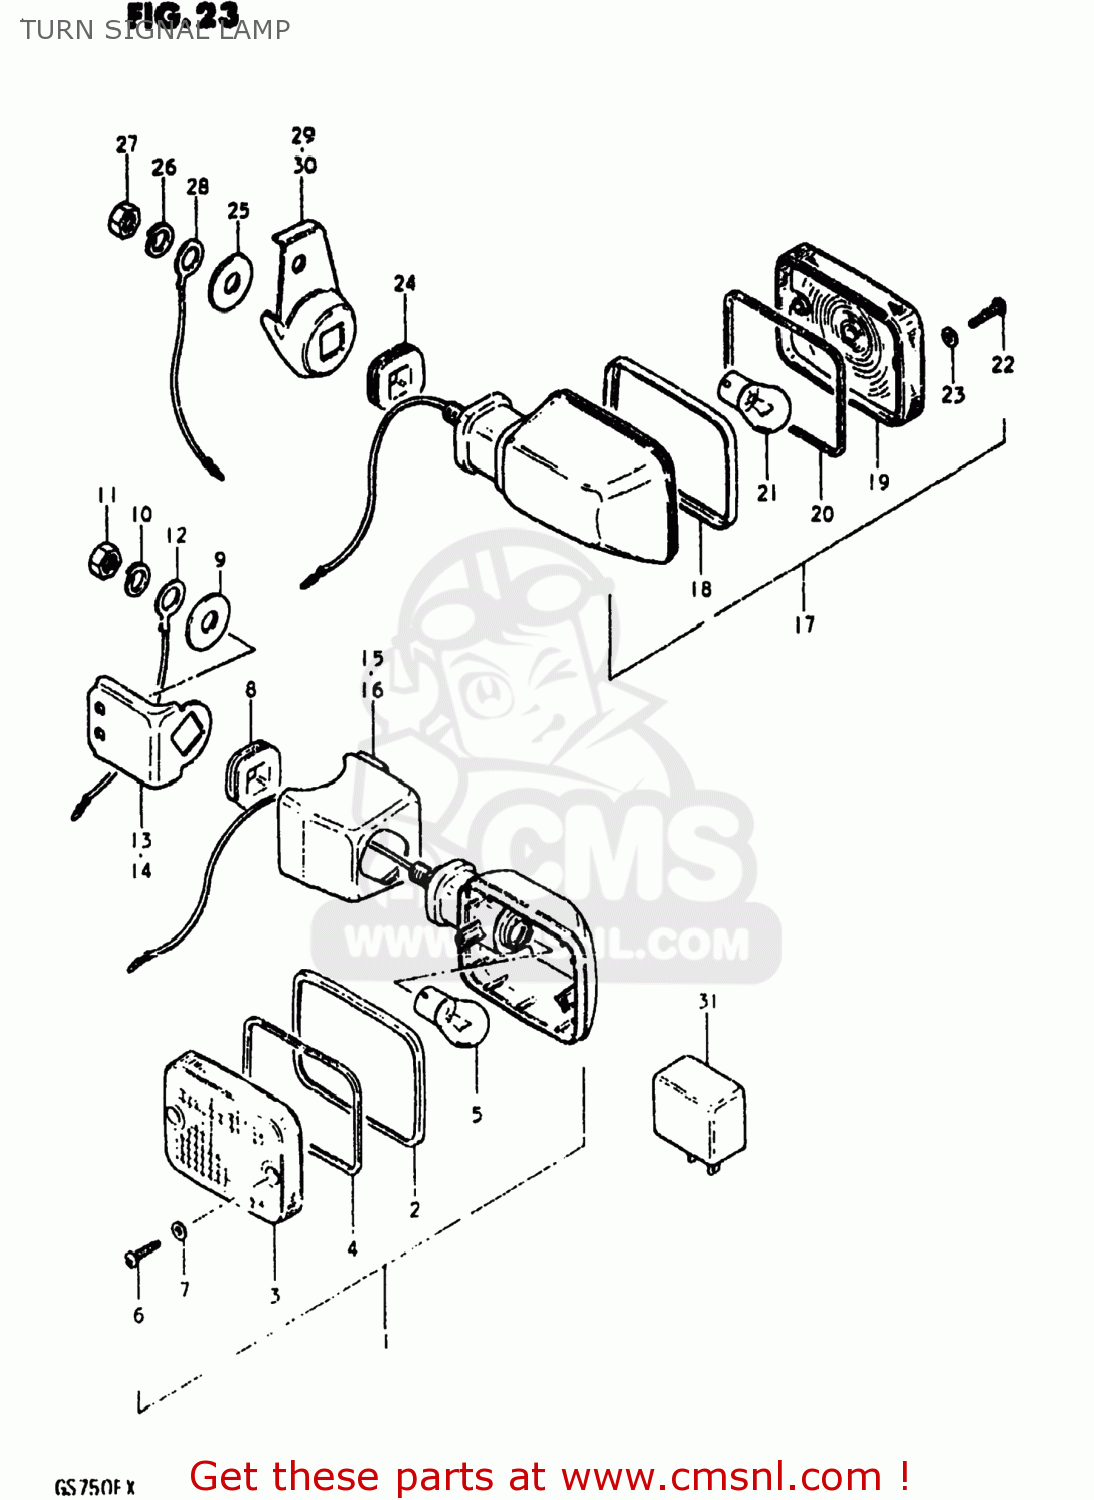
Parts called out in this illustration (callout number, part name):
1	LAMP ASSEMBLY,FRONT TURN SIGNAL
2	RIM
3	LENS
4	GASKET (NAS)
5	BULB(12V23W,STANLEY,A4577A)
6	SCREW
7	GASKET (NAS)
8	CUSHION
9	WASHER (10.5X30X2.3)
10	LOCK WASHER
11	NUT
12	WIRE,TURN SIGNAL LEAD
13	BRACKET,FRONT TURN SIGNAL
14	BRACKET,FRONT TURN SIGNAL
15	COVER,TURN SIGNAL BRACKET
16	COVER,TURN SIGNAL BRACKET
17	LAMP ASSEMBLY,FRONT TURN SIGNAL
18	RIM
19	LENS
20	GASKET (NAS)
21	BULB(12V23W,STANLEY,A4577A)
22	SCREW
23	GASKET (NAS)
24	CUSHION
25	WASHER (10.5X30X2.3)
26	LOCK WASHER
27	NUT
28	LEAD WIRE,EARTH
29	BRACKET,REAR TURN SIGNAL
30	BRACKET,REAR TURN SIGNAL
31	RELAY,TURN SIGNAL
